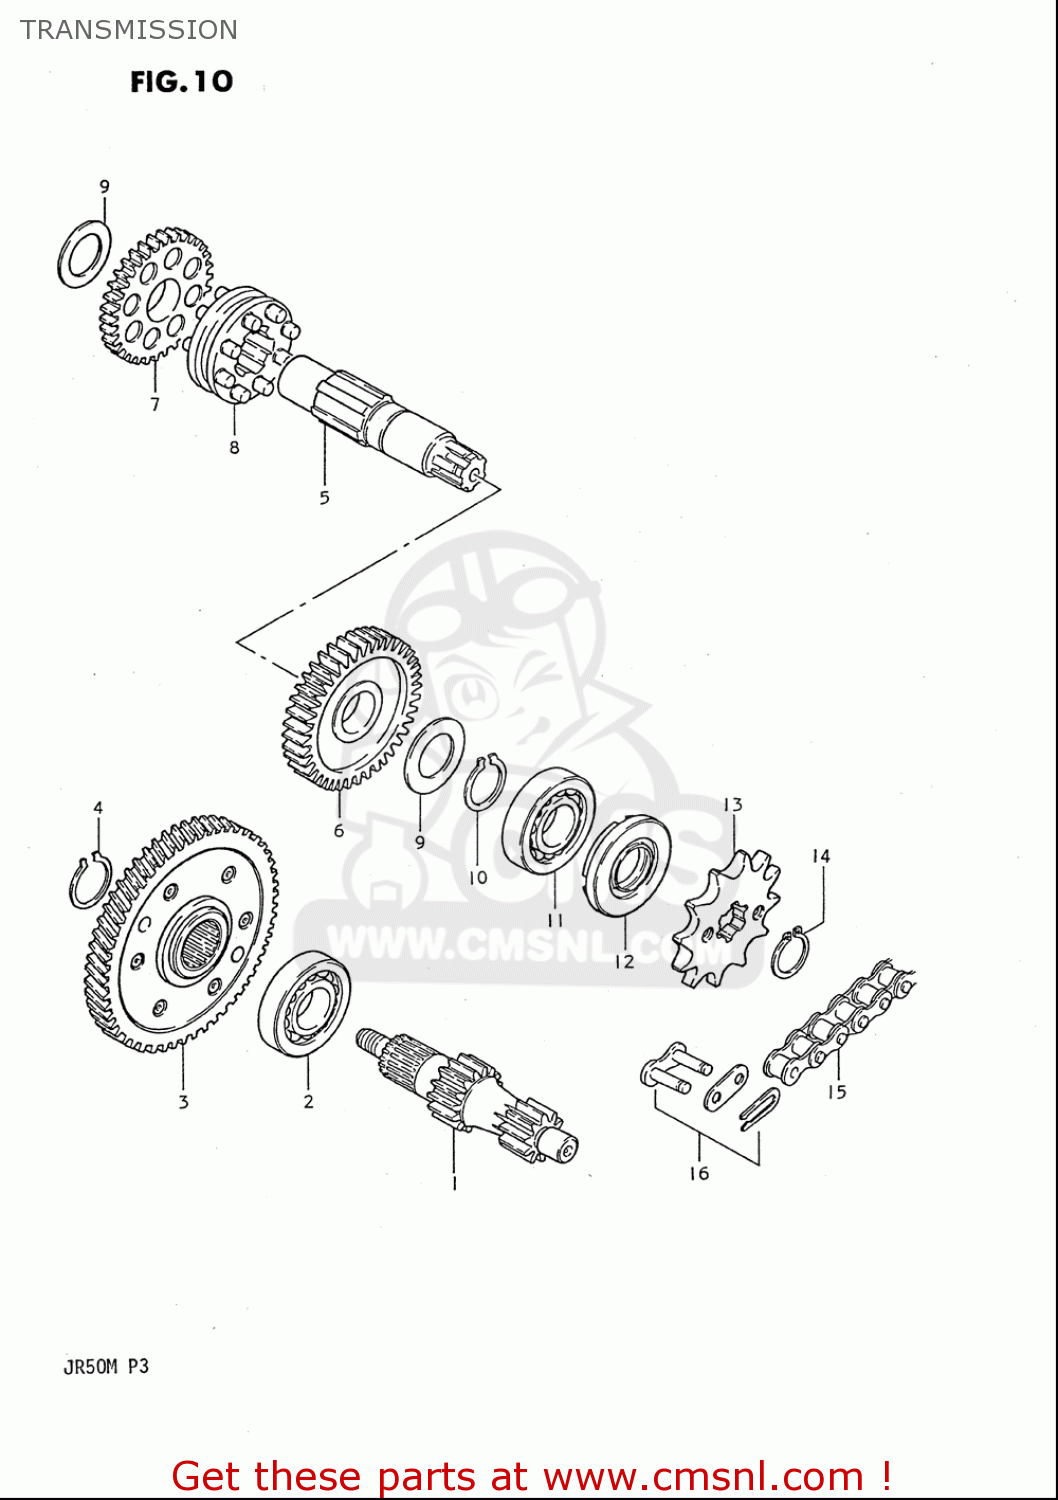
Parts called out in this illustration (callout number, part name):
1	SHAFT,COUNTER
2	BEARING(17X40X12)
3	GEAR ASSY,PRI DRIVEN
4	CIRCLIP
5	SHAFT,DRIVE
6	GEAR 1ST DRIVEN
7	GEAR 2ND DRIVEN
8	WHEEL,1ST GEAR
9	SHIM(17X30X1)
10	CIRCLIP
11	BEARING(17X40X12)
12	SEAL,OIL(17X29X7)
13	SPROCKET,ENGINE
14	CIRCLIP 16MM
15	CHAIN,DRIVE
16	JOINT
